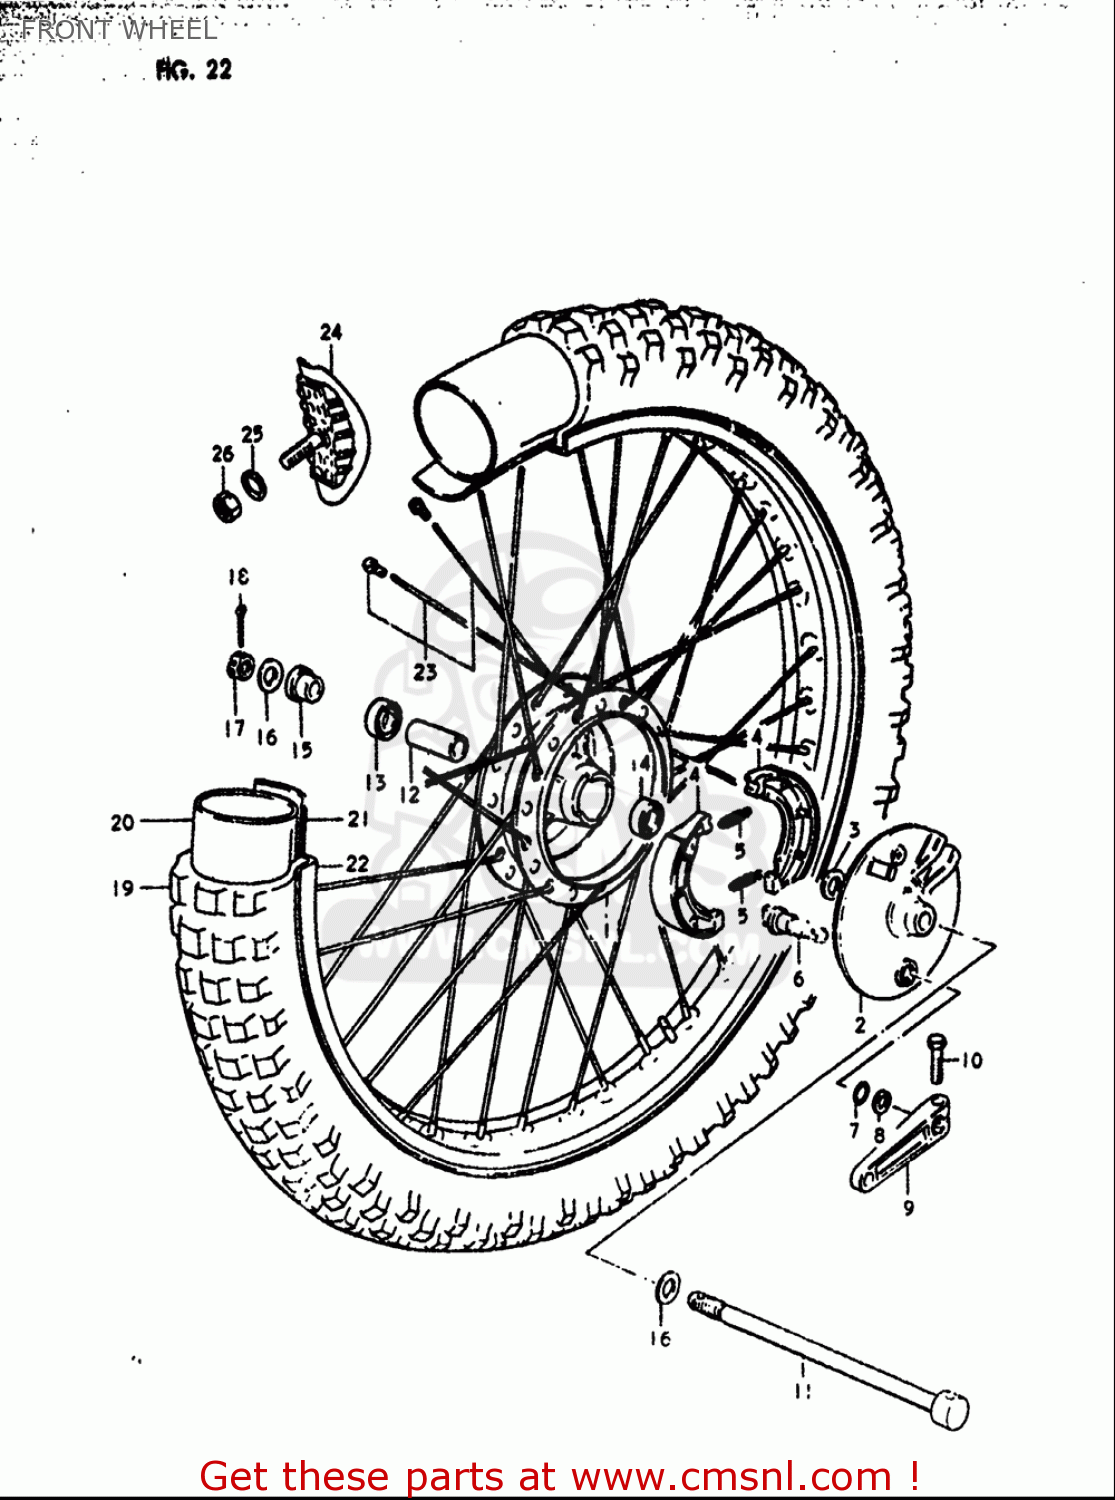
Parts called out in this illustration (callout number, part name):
5	SPRING(L:35.8)
7	O RING(D:2.5,ID:11.4)
8	WASHER(12.5X20X1)
10	BOLT
12	SPACER(12.5X19X52)
13	BEARING (12X32X10)
14	BEARING
15	SPACER,FR AXLE,R
16	WASHER
17	NUT
18	PIN
20	TUBE
21	PROTECTOR,WHEEL INNER
24	STOPPER,BEAD(1.85)
25	WASHER
26	NUT
